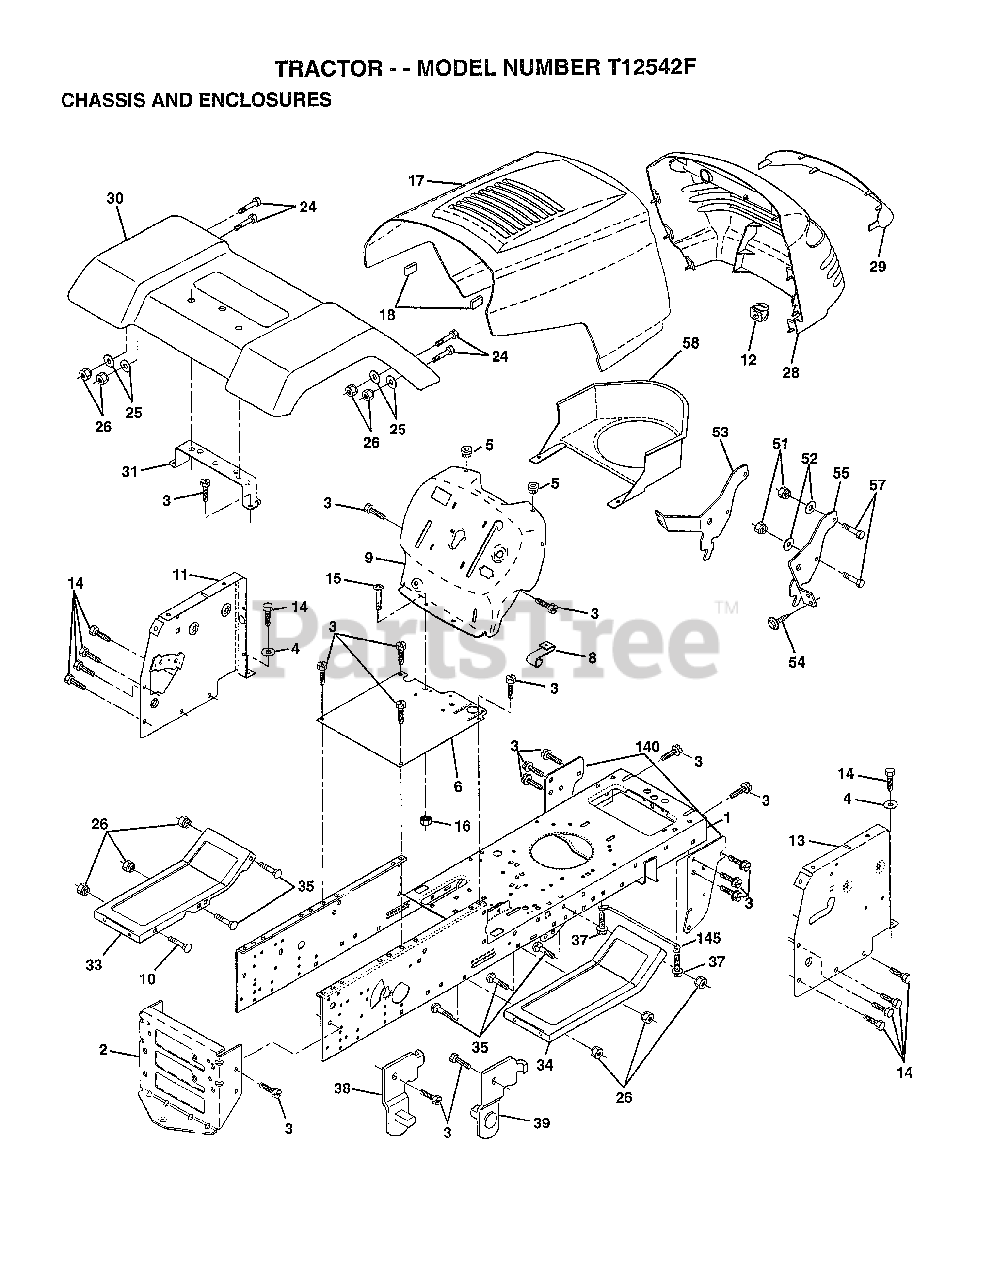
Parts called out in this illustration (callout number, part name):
3	SCREW
4	WASHER
5	BUMPER-HOOD/DASH
6	SADDLE-SILKSCREEN
8	CLIP.RETAINER
9	DASH SILKSCREEN
11	"PANEL-DASH,LH"
12	CLIP.TINNERMAN
14	SCREW LT
15	SCREW
17	HOOD.STEEL.ASSY
24	BOLT
25	WASHER
26	NUT
28	GRILLE-MS428
29	LENS GRILLE
30	FENDER PNT LT
31	BRKT FENDER
33	FOOTREST.LH.PERF.
34	FOOTREST.RH.PERF.
35	BOLT
38	BRACKET ASM LH
39	BRACKET ASM RH
51	NUT
52	WASHER
53	BRACKET.GRILLE.LH
54	SCREW.HEX.WS.HD
55	BRACKET.GRILLE.RH
58	AIR DUCT
140	BRKT SUSPENSION
145	"ROD POVOT,CHASSIS"
